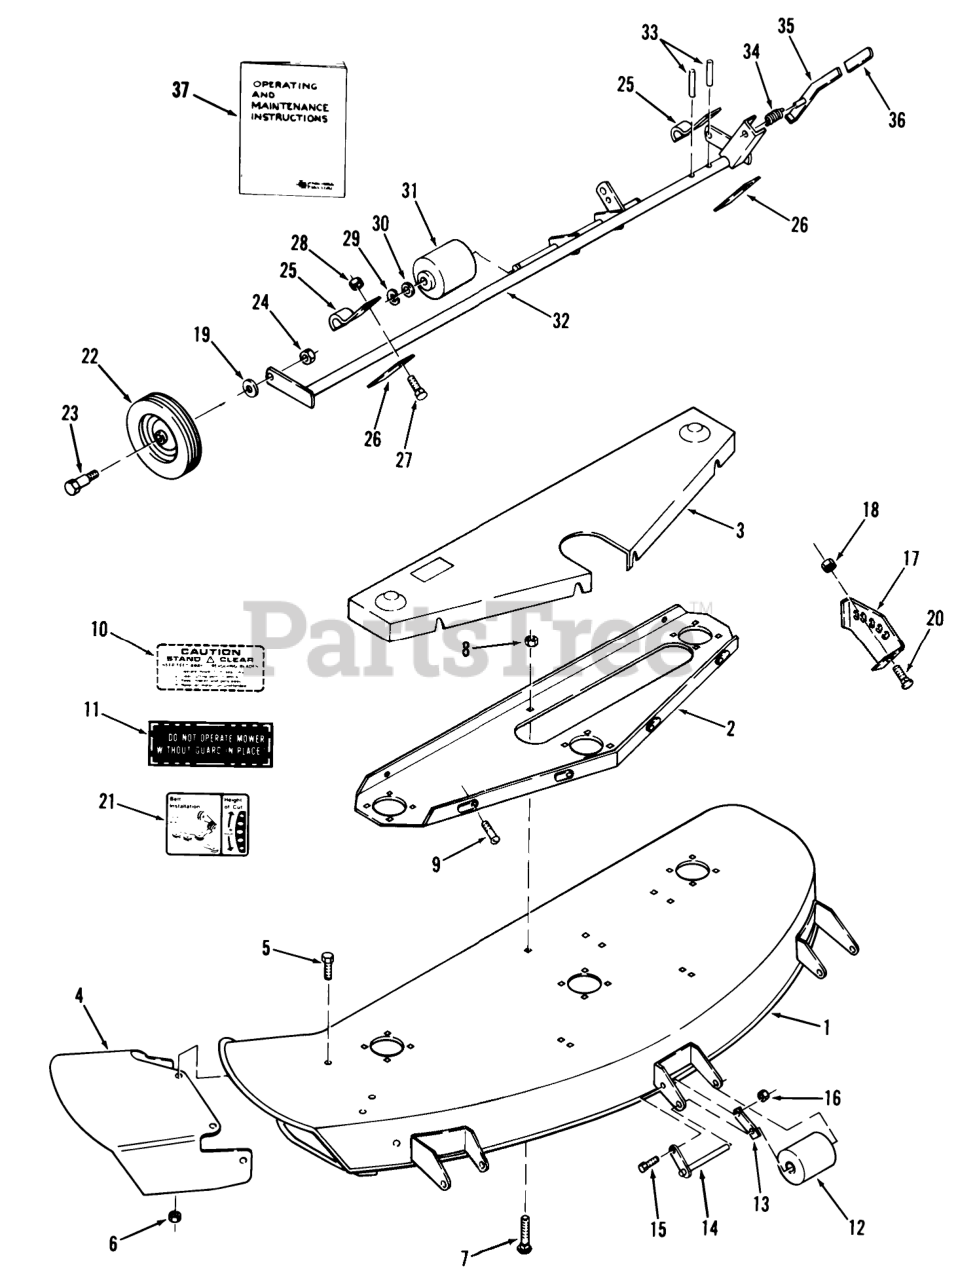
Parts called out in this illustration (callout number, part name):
23	BOLT-SHOULDER
33	PIN-SPIROL
34	SPRING-COMPRESSION
37	Operating and Maintenance Instructions
